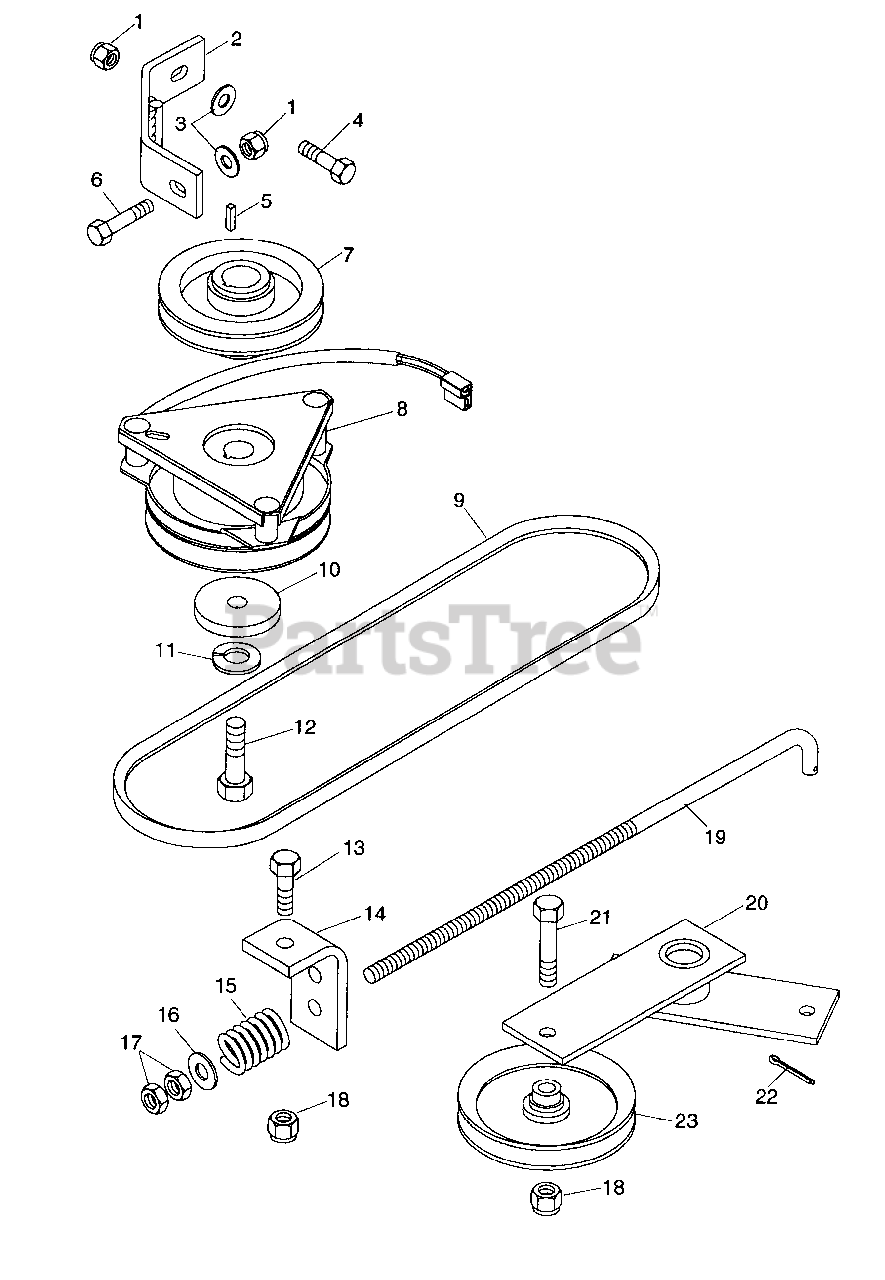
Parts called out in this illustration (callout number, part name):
1	Nut-Locking-Nylon .312-18
2	Weldment, Clutch Stop
3	Washer-Flat-Steel .344 x .688 x .065
4	Bolt-Hex .31-18 x 1.00 Grade 5
5	Key-Square .248 x 1.25 x .248
6	Bolt-Hex .31-18 x 1.25 Grade 5
7	Sheave
8	Clutch, Electric
9	V-Belt A-Section 19.65 x 17/32
10	Washer-Special .469 x 2.000 x .250
11	Washer-Lock .44
12	Bolt-Hex .44-20 x 1.50 Grade 5
13	Bolt-Hex .38-16 x 1.00 Grade 5
14	Bracket
15	Spring-Compression .072 x .561 x 2.50
16	Washer-Flat-Steel .406 x .812 x .065
17	Nut-Hex .375-16
18	Nut-Locking-Nylon .375-16
19	Rod, Idler Right Hand
19	Rod, Idler
20	Weldment, Idler
21	Bolt-Hex .38-16 x 1.875
22	Pin-Cotter .09 x .75
23	Pulley-Idler 4.50 x .380
